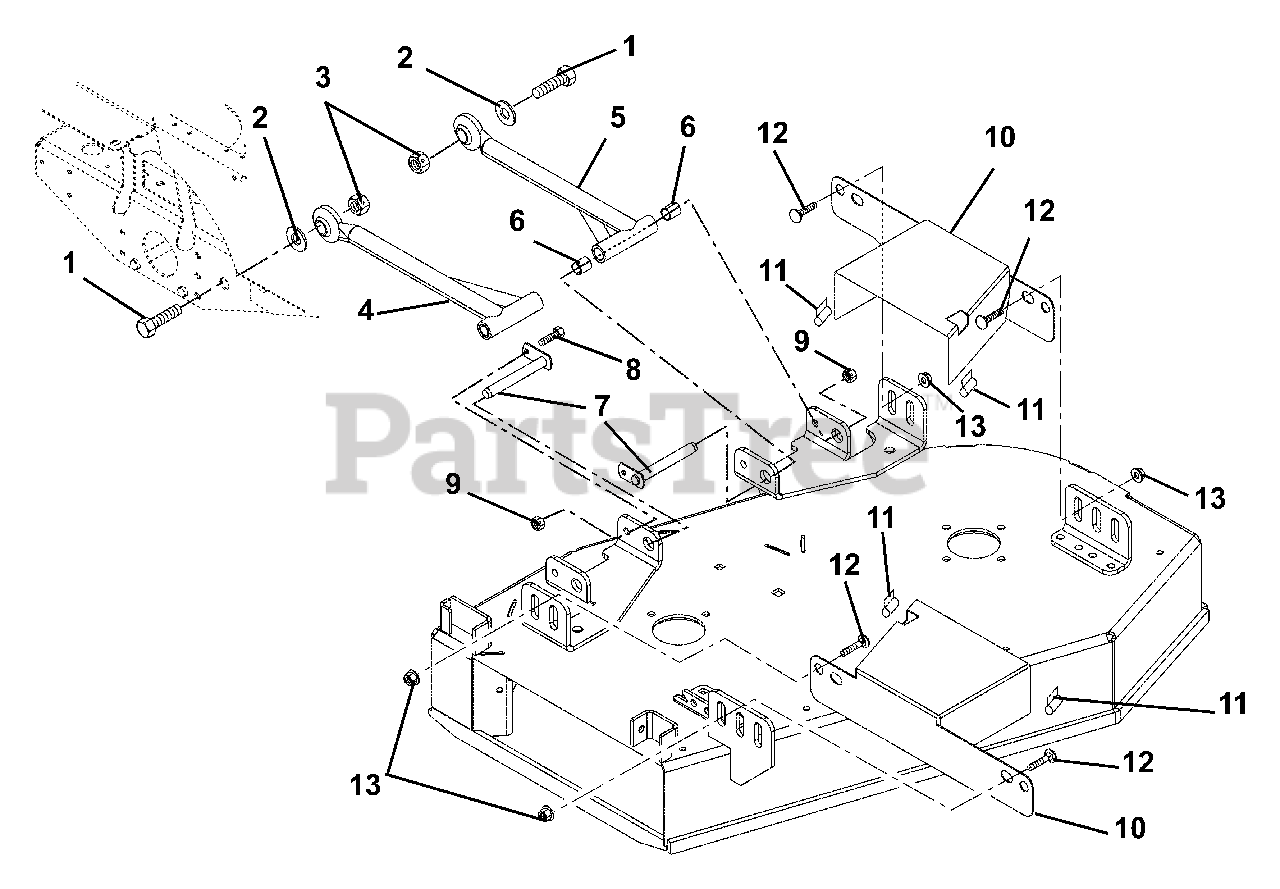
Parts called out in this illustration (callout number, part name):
1	Bolt, Hex .875-9 x 3.00
2	Bushing, Sleeve .875 x 1.25 x .531
3	Nut, Locking Center .875-9
4	Assembly, Mower Mounting
5	Arm, Mower Mounting
6	Bearing, .75 x .875 x 1.00
7	Weldment, Mower Mounting Pin
8	Bolt, Hex .38-16 x .88
9	Nut, Locking Top Flange .38-16
10	Guard, 34" Belt
11	Seal, Trim-LOK Bulk .06 Bubble
12	Bolt, Round Head Square Neck .50-13 x 1.00 Grade 5
13	Nut, Locking Top Flange .50-13
